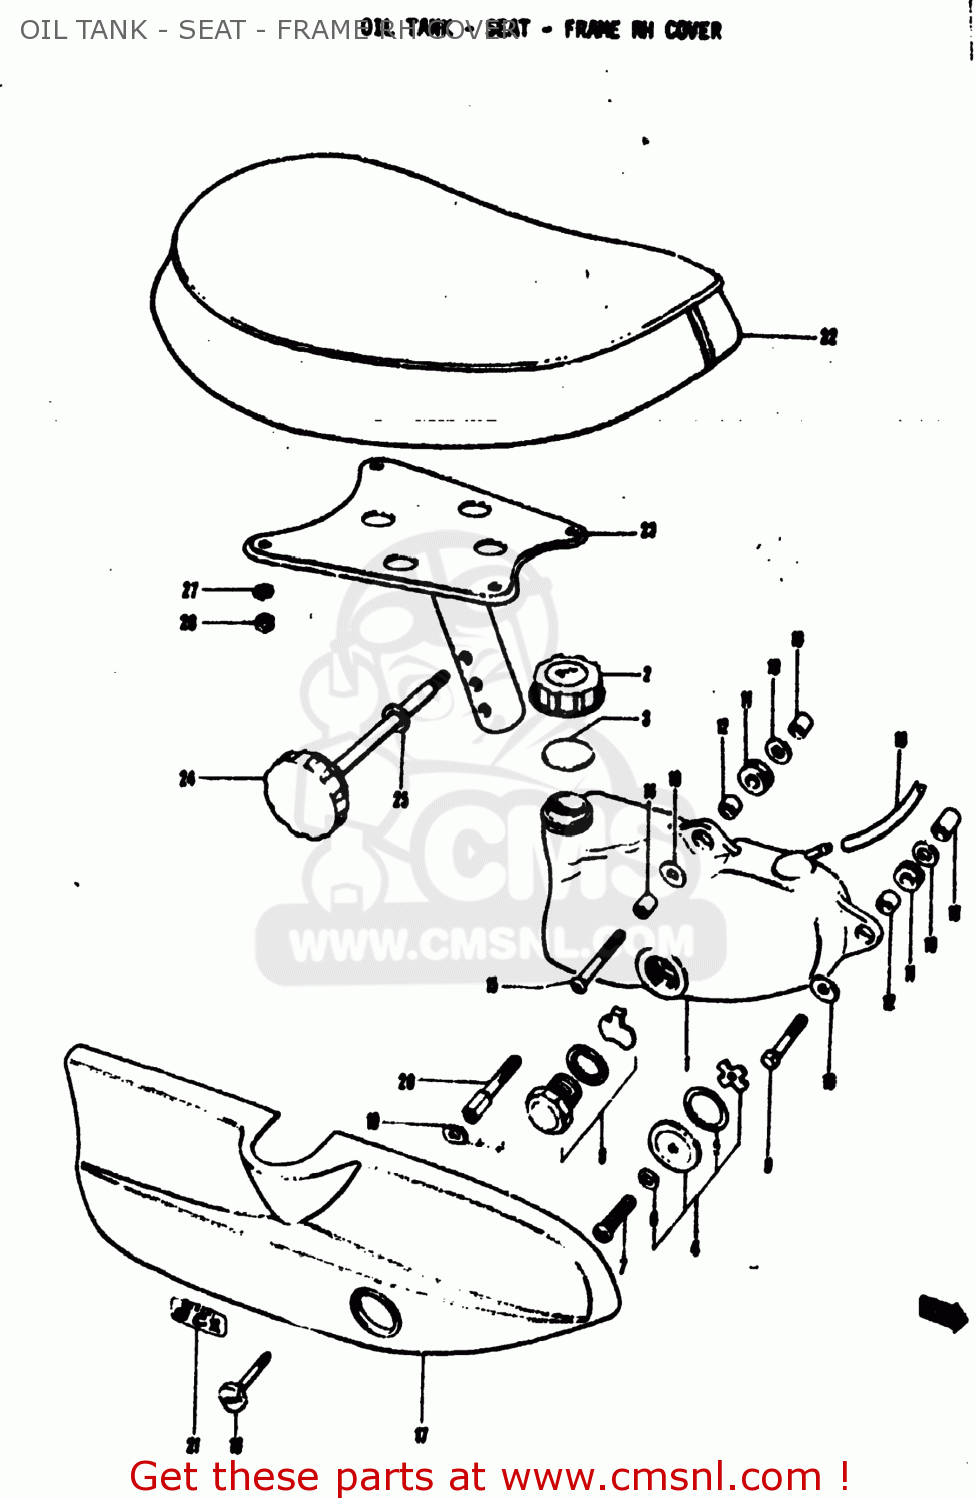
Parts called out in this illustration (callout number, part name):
2	CAP,OIL TANK
3	GASKET,OIL TANK CAP (NAS)
4	LENS SET,OIL INSPECTION
5	O RING(D:3,ID:23)
6	GASKET(5X9.5X1) (NAS)
7	SCREW
8	LENS SET,OIL LEVEL
9	BOLT
10	WASHER
11	CUSHION
12	SPACER (6.8X10X10)
13	SPACER(6.8X10X24.2)
14	SPACER (6.1X8X12)
15	SCREW 6X60
16	HOSE
18	KNOB, FRAME COVER
19	NUT (5MM)
21	EMBLEM,CCIS
26	NUT
27	LOCK WASHER
